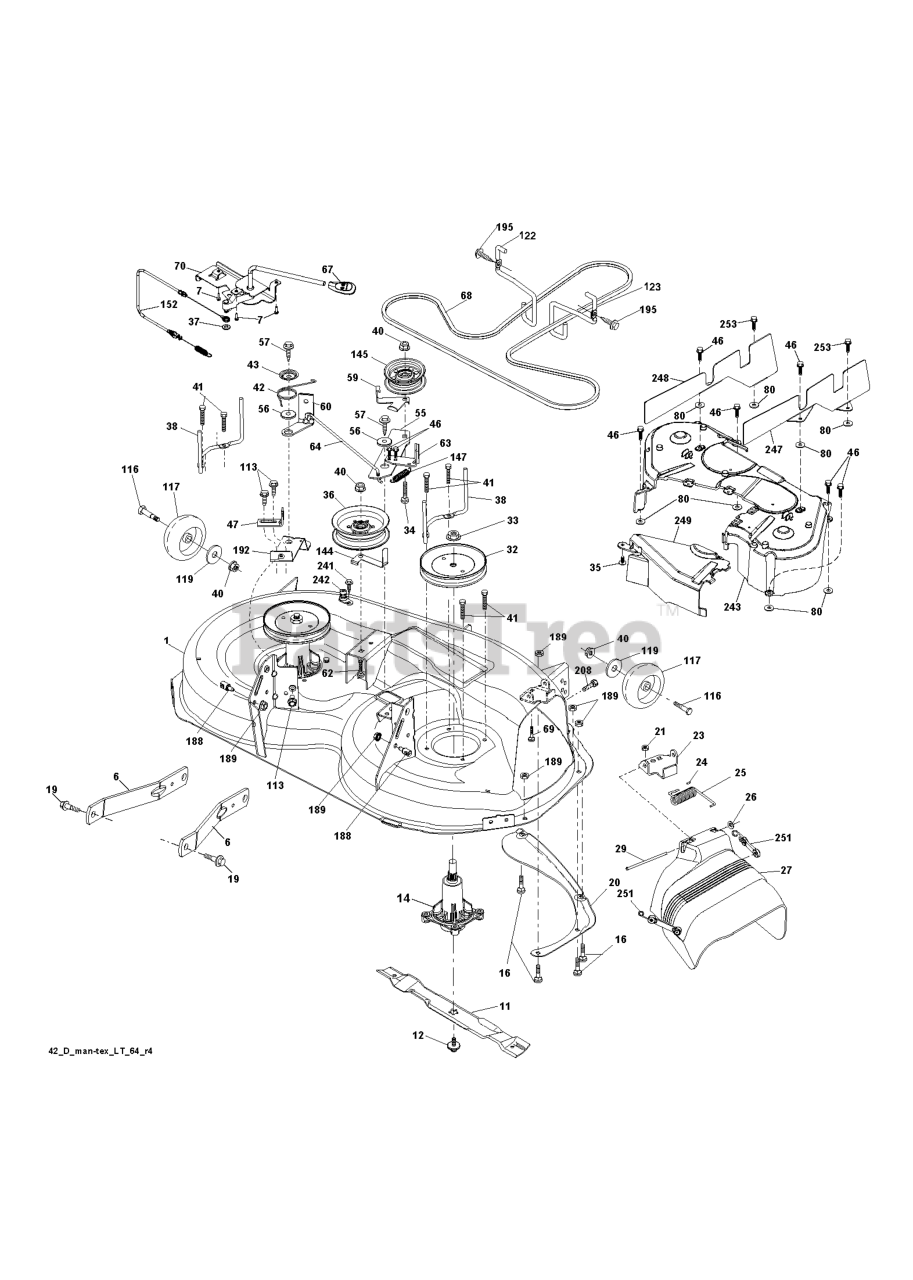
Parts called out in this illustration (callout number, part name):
1	Weldments
6	ARM.SUSPENSION.MOWER.R
11	42" HI-LIFT BLADE
12	SCREW.SEMS.7/16-20X1.HEX.HEAD
14	KIT.MANDREL.NONGREASE.TALL
16	BOLT ROUND HEAD SQUARE NECK BO
19	BOLT.SHOULDER
20	BAFFLE.VORTEX
23	BRKT.DEFLECTOR.38"2005+
24	CAP-SLEEVE LT
25	SPRING.TORSION.DEFLECT
26	NUT PUSH M
27	Deflectors
32	PULLEY.MANDREL.5.438.PD
34	GSPW Bolts
35	FASTENER.XMAS.TREE
36	PULLEY.IDLER.2006
37	WASHER PLAIN WASHER 3/8 X 0.08
38	KEEPER.BLT.PNT.MNDRL.PULL.6.25
40	NUT LOCK FLG 3/8-16 UNC
41	BOLT.HEX.WASHR.HED.313-18X1.19
42	SPRING.TORSION.BRAKE
43	SRPING.TORSION.RETAINE
46	SCREW.1/4-20X5/8
47	BRKT.CLUTCH.CABLE
55	IDLER.ARM.42"
56	SPACER.RETAINER
57	SCREW 3/8-16X1
59	GUARD, BELT
60	ARM BRAKE MOWER
63	ARM BRAKE MOWER
64	LINKAGE.BRAKE.ASM.ZINC
67	HANDLE.CLUTCH.CABLE.LT
70	CLUTCH.ASM.MANUAL.YT.PREDATORQ
80	PALNUT 1/4
113	BOLT.5/16HEX.WHS.HD
117	WHEEL.GAUGE.RALLY.NARROW
122	KEEPER BELT ENGINE LH
123	KEEPER BELT RH
144	KEEPER.BELT.MOWER
145	PULLEY.IDLER.48"PRIMARY
147	RETURN SPRING
152	CABLE.MECHANICAL.CLUTCH
188	STUD.W/"D"ANTI-ROTATION
192	BRKT.BRAKE.STAND.LH.
195	SCREW, 3/8-16X3/4
208	SCREW 3/8-16X1/2
241	SCREW.TT.#10-32X.5.3/8.FLANGE
242	PORT.WASHOUT
243	COVER DECK
247	SHIELD DECK RIGHT
248	SHIELD DECK LEFT
249	COVER CABLE CLUTCH
251	ELASTIC STRAP KIT
253	SCREW
